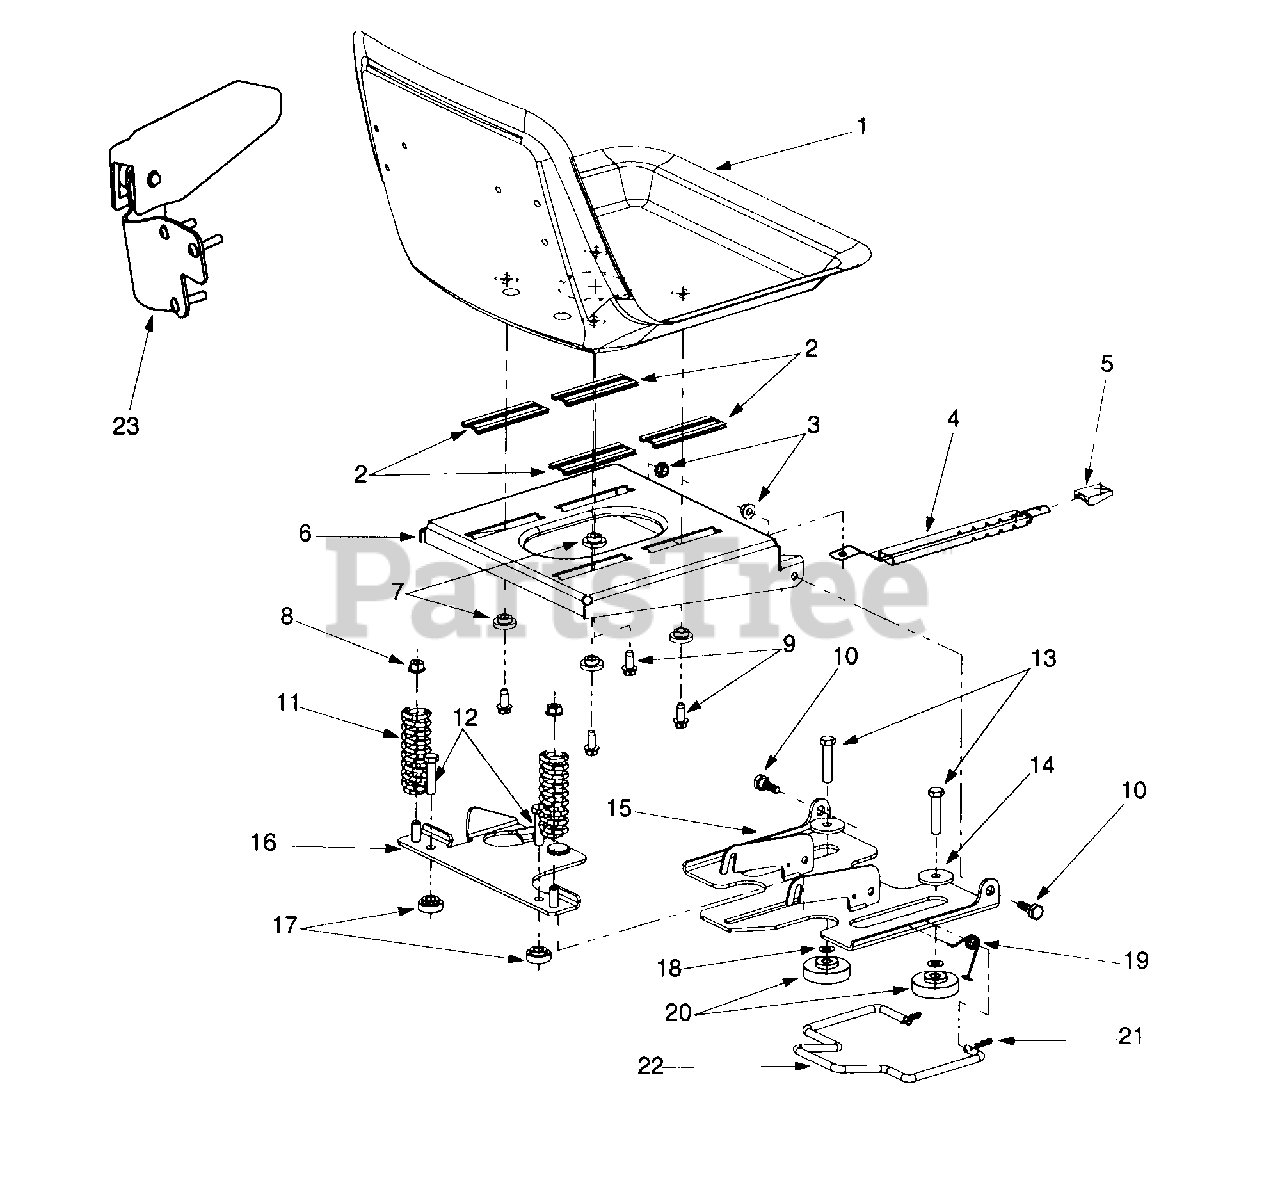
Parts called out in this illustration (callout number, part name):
1	Seat Assembly
2	Seat Slide
3	Flange Lock Nut 5/16-18
4	Spring Index
5	Knob
6	Bracket Assembly
7	Shoulder Spacer
8	Flange Lock Nut 3/8-16
9	Hex Washer Screw 5/16-18 x .75
10	Shoulder Screw
11	Compression Spring 1.28 OD x 3.5
12	Hex Cap Screw 3/8-16 x 1.5
13	Hex Cap Screw 3/8-16 x 1.75
14	Flatwasher
15	Seat Bracket Assembly
18	Thrust Washer
19	Torsion Spring
20	Shoulder Spacer
21	Cotter Pin
23	Seat Arm
